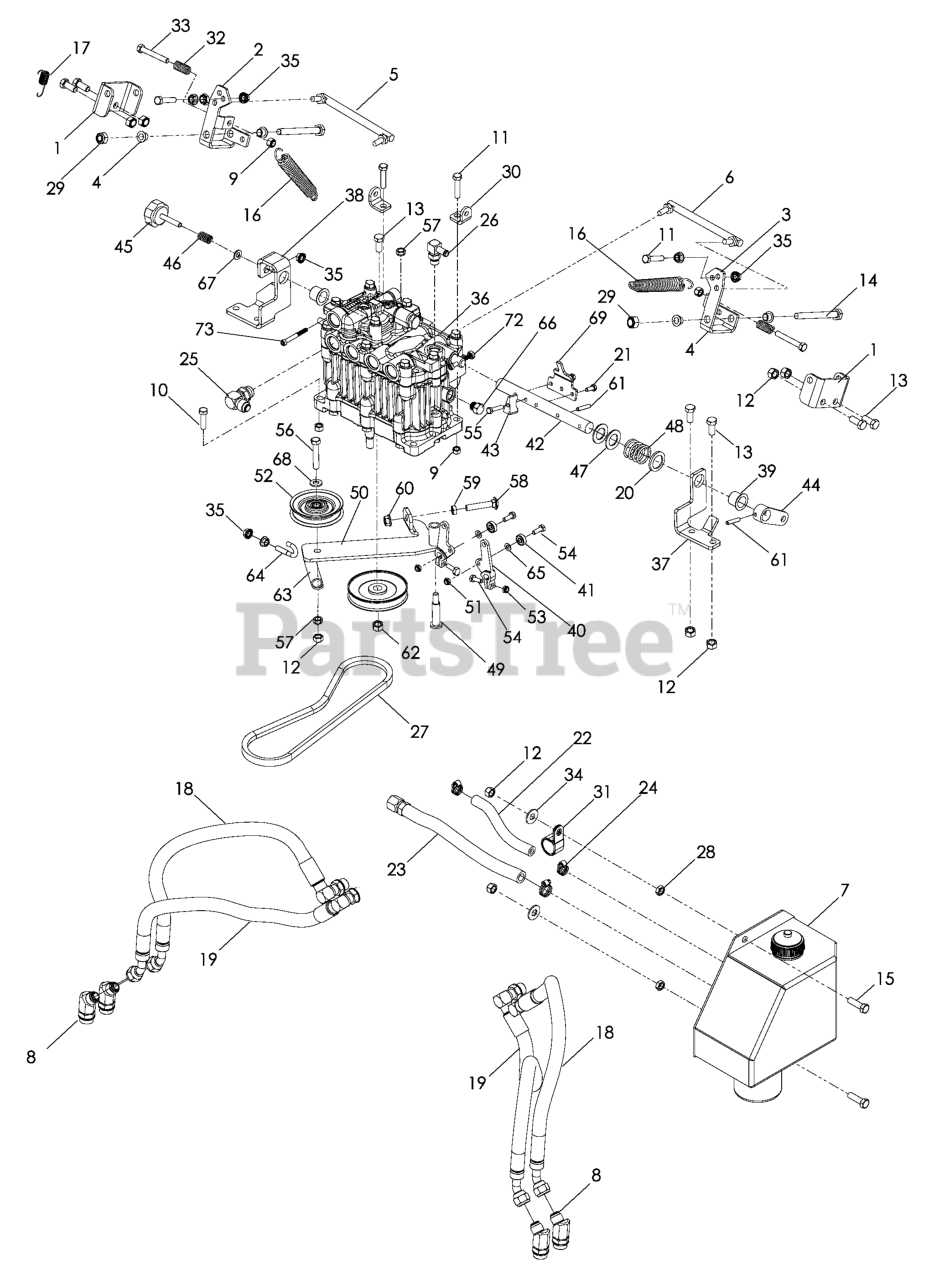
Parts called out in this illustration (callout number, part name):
1	BRACKET - U
2	BELLCRANK LH PAINTED
3	BELLCRANK RH PAINTED
4	BEARING - FLANGE 10MM
5	LINK - CONTROL, RH WB
6	LINK - CONTROL, LH WB
7	RESERVIOR
8	45 DEG STRAIGHT THD ELBOW 8-10
9	NUT 5/16 NYLOC
10	HCS 5/16C X 1 1/4
11	CAPSCREW 5/16 X 1/1/2 HEX HEAD
12	NUT 3/8-16 NYLOC
13	HCS 3/8-16 X 7/8 GR 5 ZD
14	HCS M10-1.58 X 100MM GR8.8 ZD
15	HCS 3/8C X 1 1/4 GR5
16	SPRING-TRANS
17	SPRING, EXTENSION
20	WASHER, FIBER
21	HCS M6-1.0 X 16MM GR 8.8 ZN
22	HOSE - RETURN
23	HOSE - SUCTION
24	HOSE CLAMP T-1865
25	ELBOW, 90 DEGREE
26	FITTING, 90 DEG 9/16-18 X 3/8
27	V-BELT PUMP DRIVE
28	NUT 3/8-16 HEX JAM
29	NUT, M10-1.5 NYLON RING ZD
30	BRACKET, SPRING, BLK
34	WASHER 3/8 FLAT
35	NUT 5/16C WHIZ
36	PUMP, DUP10E
37	SUPT - CAM LH
38	SUPT - CAM, RH PAINTED
39	BEARING - FLANGE, 20MM
40	ARM - HYDRO
41	BEARING - FOLLOWER
42	SHAFT - CAM
43	CAM - TRACKING
44	ARM - SPEED CONTROL
45	ADJUSTMENT KNOB
46	SPRING - COMPRESSION
47	WASHER - 20MM
48	SPRING - COMPRESSION
49	PULLEY, PUMP
51	BOLT, SHOULDER
53	JAM NUT 1/4C (2 2 PW01)
54	HCS 1/4C X 3/4 HCS
55	BOLT - M6-1.0 X 30MM GR 8
56	HCS 3/8C X 2
57	NUT HEX 3/8-16 NYLON, THIN
58	RHSNB 3/8C X 2
59	NUT 3/8-16 HEX JAM
60	NUT 3/8C WHIZ
61	ROLL PIN - 6 MM X 30 MM
62	NUT M10-1.5 L/H HEX
63	SPRING AXLE AERATOR
64	J-BOLT
66	PLUG, 6408-6
67	FLAT WASHER 5/16 SAE
68	WASHER 3/8 SAE FLAT
69	PLATE - STOP, BLK
70	NUT M8-1.25 TOP NYL GR10 ZD
71	WASHER.LOCK.HVY.HLCL.SPR.5/16
72	NUT 10-24 NYLOC
73	SCR, #10-24X2 SOCKET HEAD CAP
